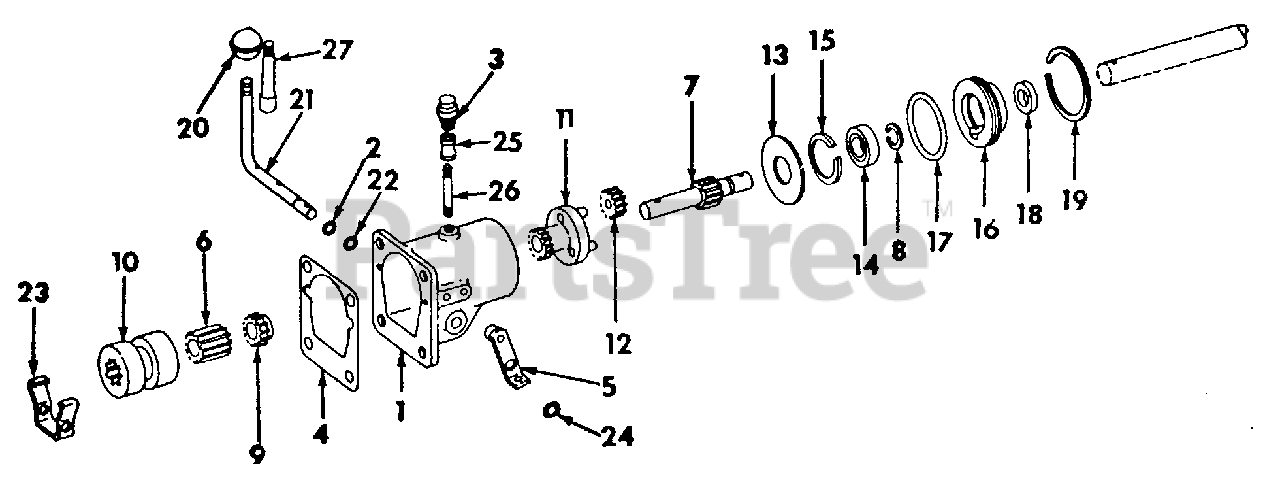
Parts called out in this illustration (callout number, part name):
1	Housing Assy, Creeper Drive
2	O-Ring, 3/8 X 1/2 X 1/16
3	Breather, Creeper Drive Housing
4	Gasket, Creeper Drive Housing
5	Lever Assy, Creeper Shift Poppet
6	Coupling Assy, Driven
7	Shaft, Creeper Drive Input
8	Ring, Creeper Drive Input Shaft Snap
9	Coupling, Direct Drive
10	Collar, Shifter
11	Carrier Assy, Planet
12	Gear, Planet
13	Washer, Planet Gear Thrust
14	Bearing, Creeper Input Shaft Ball
15	Ring, Input Shaft Brg Snap
16	Cage, Input Shaft Brg
17	O-Ring, 2-7/16 X 2-5/8 X 3/32
18	Seal, Input Shaft Brg Cage Oil
19	Ring, Input Shaft Brg Cage Retainer Snap
20	Knob, Creeper Shift Lever
21	Lever, Creeper Shift
22	O-Ring, 1/4 X 3/8 X 1/16
23	Yoke, Creeper Shift
24	Spacer, Poppet Lever
25	Not used in this application
26	Not used in this application
27	Not used in this application
